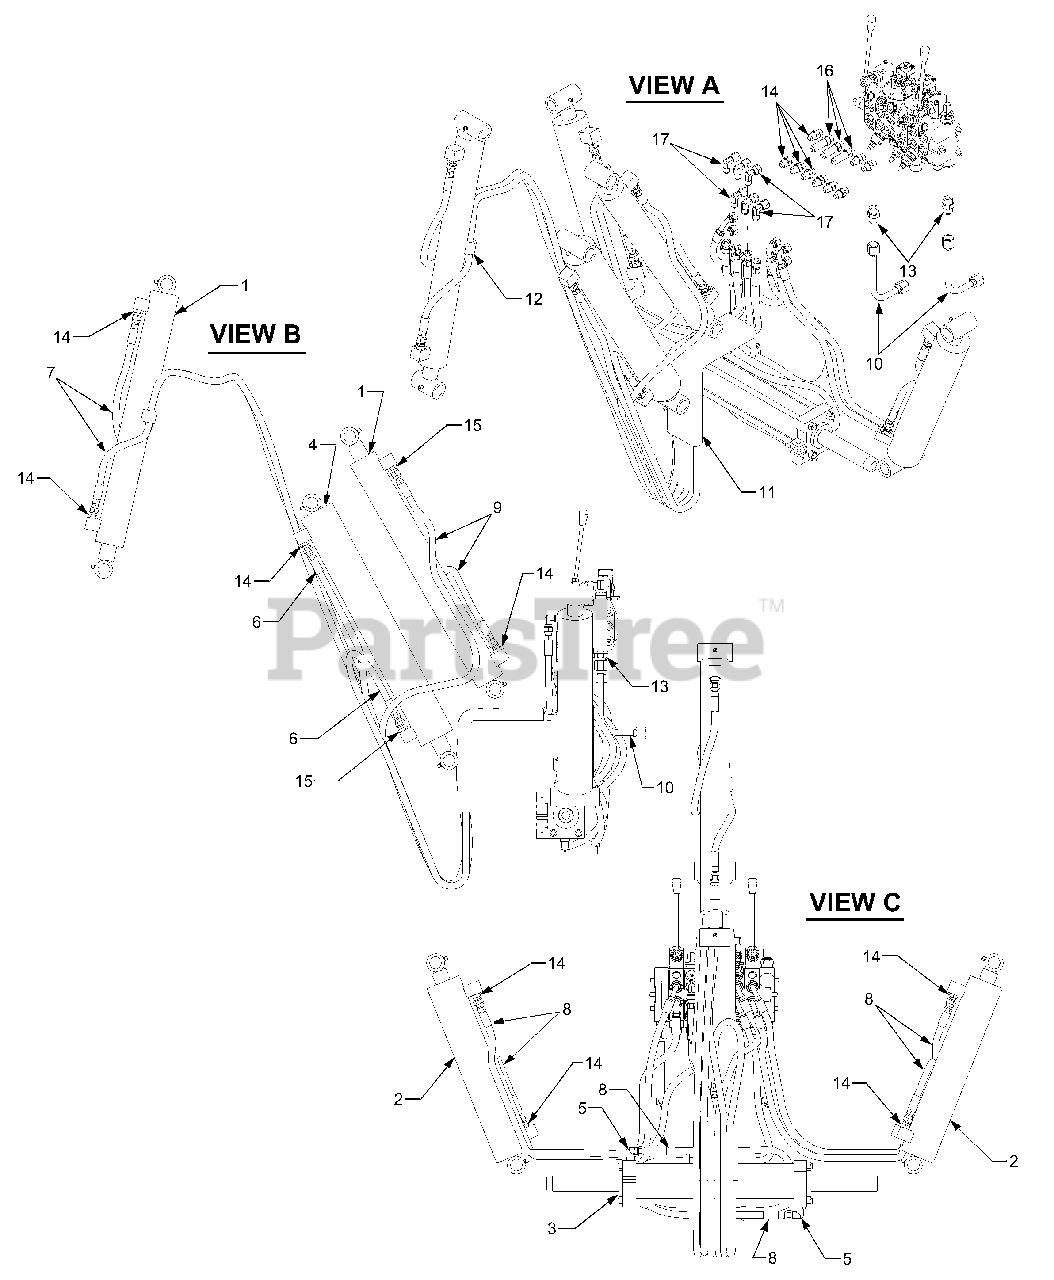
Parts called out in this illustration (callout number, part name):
1	Cylinder, Bucket & Dipper Arm
2	Cylinder, Stabilizer Arm
3	Cylinder, Boom Angle
4	Cylinder, Boom
5	Fitting, 90 Degree
6	Hose, Boom Cylinder
7	Hose, Bucket Cylinder
8	Hose, Swing-Stabilizer Cylinder
9	Hose, Dipper Arm Cylinder
10	Tube, Valve Inlet
11	Sleeve, Hose Guard
12	Clamp, Hose
13	Fitting, Straight - 8 Orb
14	Fitting, Straight - 6 Orb
15	Fitting, Straight - 6 Orb:Restricted
16	Fitting, Straight - 6 Orb:Extended
17	Fitting, 90 Degree Elbow (swivel)
